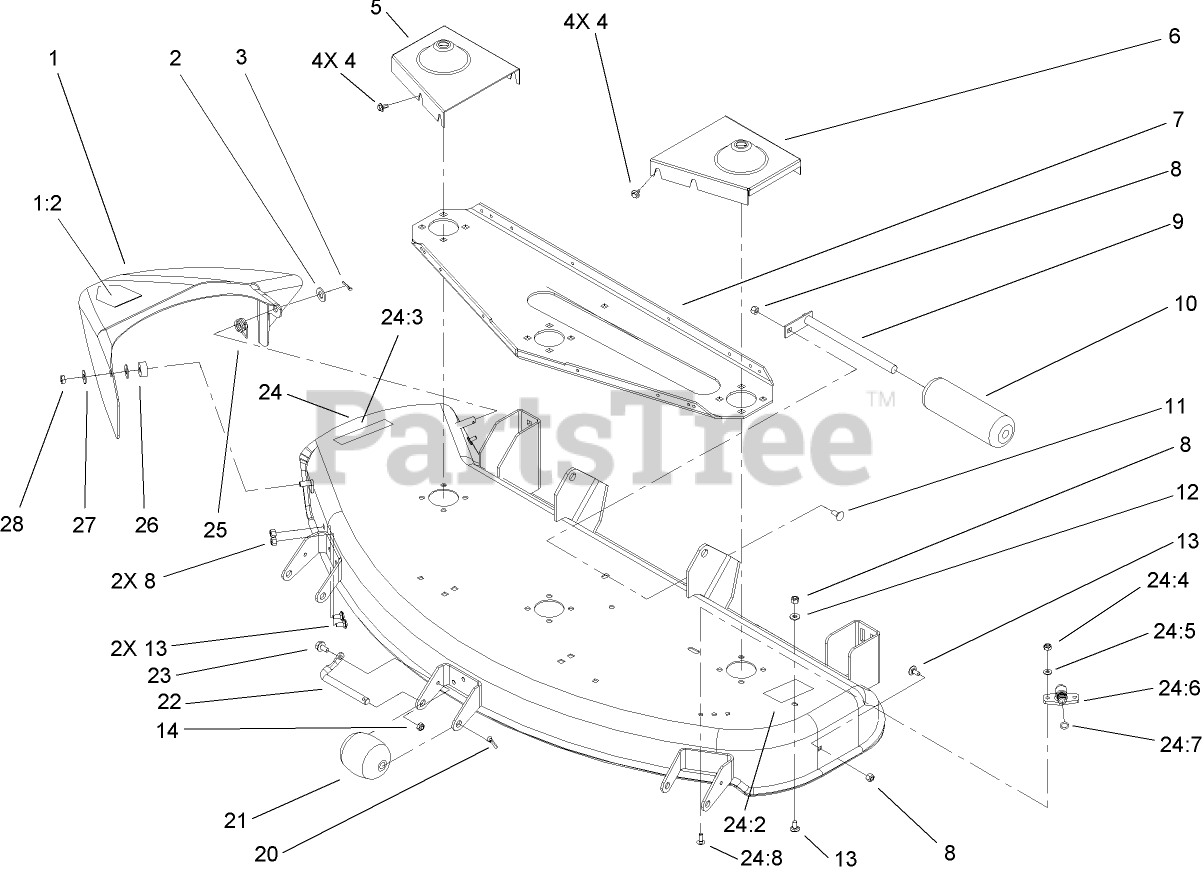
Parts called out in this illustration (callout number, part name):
1	CHUTE ASM
1:2	DECAL-DANGER
2	WASHER-FLAT
3	PIN-COTTER
4	SCREW-HHFTF
5	COVER-BELT, RH
6	COVER-BELT, LH
7	PLATE-REINFORCEMENT,DECK
8	NUT-LOCK, NI
9	ROLLER-SHAFT
10	ROLLER-ANTI SCALP
11	BOLT-CARR
12	WASHER-FLAT
13	SCREW-CARR
14	NUT-LOCK, NI
20	PIN-COTTER
21	ROLLER
23	SCREW-HH
24	48 IN DECK/DECAL ASM
24:2	DECAL-DANGER
24:3	DECAL-DANGER
24:4	NUT-LOCK, NI
24:5	WASHER-FLAT
24:7	O-RING
24:8	BOLT-CARR
25	SPRING-DEFLECTOR
26	BUSHING-PIVOT
27	WASHER
28	NUT-HJ
